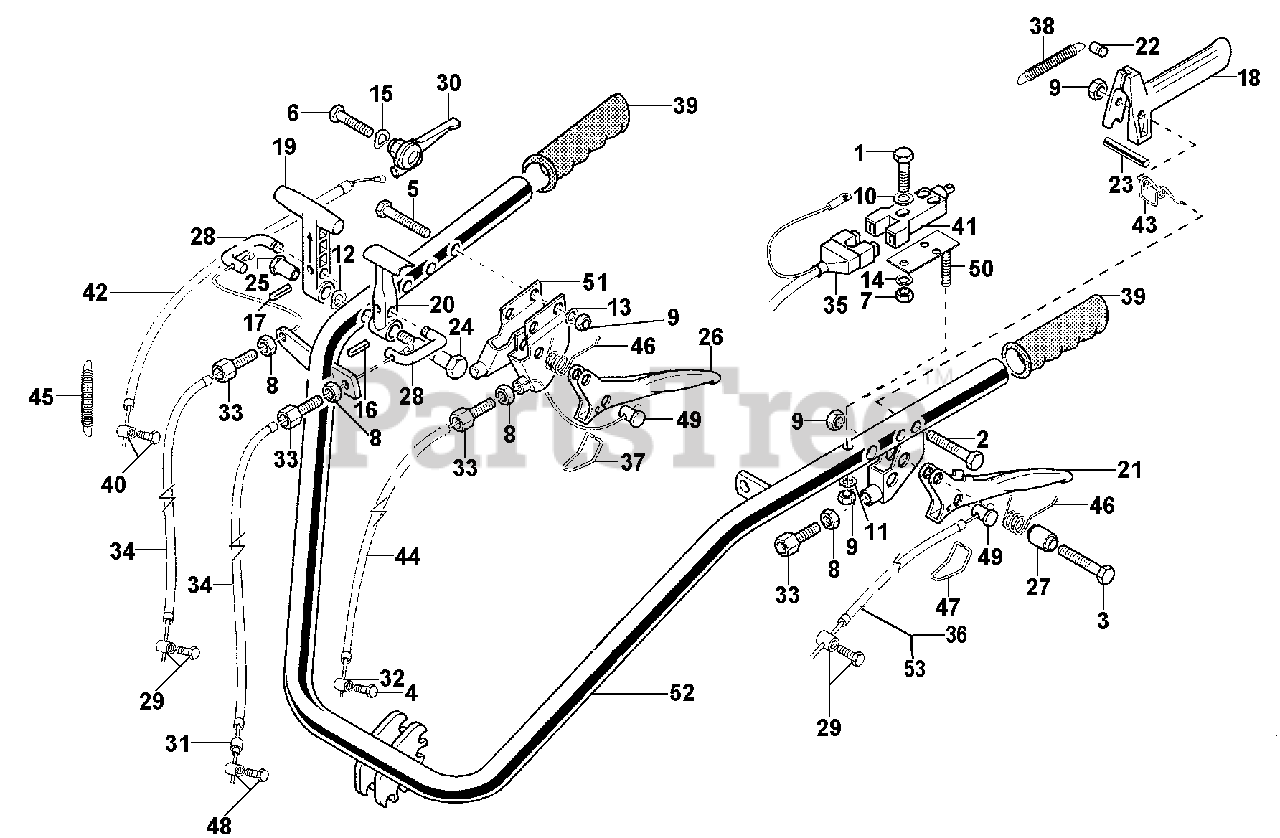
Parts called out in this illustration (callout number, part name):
1	SCREW, M4X25
2	SCREW, M6X45
3	SCREW, M6X25
4	SCREW, M6X16
5	SCREW, M6X35
6	SCREW, M8X35
9	NUT, SELF LOCKING, M6
10	FLAT WASHER, M4.3
11	WASHER, FLAT 6.4
13	WASHER, LOCK, M6.4
14	LOCK WASHER, M4.3
15	WASHER, LOCK, M8.4
16	PIN, LOCKING M4X20
17	PIN, LOCKING, M4X20
18	MOTOR STOP LEVER
19	REVERSER LEVER
20	LEVER DIFFERENTIAL LOCKING
21	CLUTCH LEVER
23	LEVER STOP FOR MOTOR STOP
25	DRILLED PIN
27	LEVER SPACER
29	CLAMP, CABLE
30	LEVER, ACCELERATOR
32	PIN, CABLE CLAMP
33	SCREW, ADJUSTING M8
34	CABLE, REVERSE
35	SWITCH WIRING HARNESS
36	CABLE, CLUTCH RECOIL START
40	CLAMP, CABLE, VANGARD
41	STOP SWITCH
42	THROTTLE CABLE,
43	MOTOR STOP LEVER SPRING
44	CABLE, BRAKE
45	SPRING, KOHLER
46	LEVER SPRING
48	CABLE CLAMP
50	SWITCH PLATE
51	COUPLING FOR DOUBLE LEVER
53	CABLE, CLUTCH ELECTRIC START
